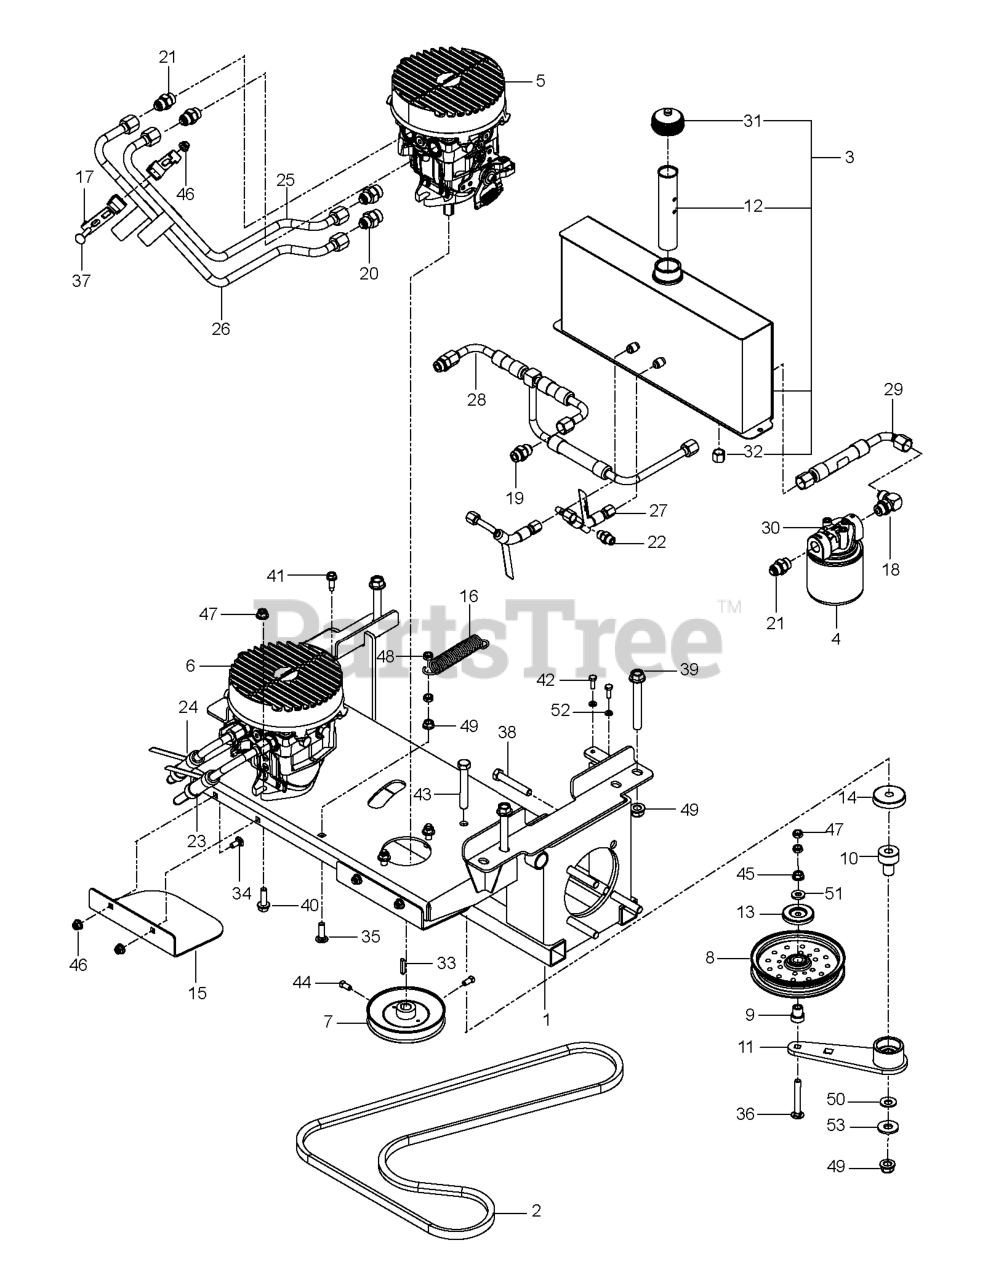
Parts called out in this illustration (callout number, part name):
1	FRAME, NYDR SUB, BLK
2	BELT, "B", 75.5"
3	ASSEMBLY, RESERVOIR, OIL
4	FILTER 25 MICRON
5	HG_PUMP, 12CC RT
6	HG_PUMP, 12CC LT
7	PULLEY, PUMP 15MM
8	IDLER, FLAT, 5.5"
9	PIVOT, IDLER
10	PIVOT, BEARING
11	ARM, IDLER, STEEL, W/BGS
12	TUBE, ANTI-SPLASH
13	DUST SHIELD
14	SHIELD, DUST
15	SHIELD, PULLEY, BLK
16	SPRING, PUMP
17	ASM, VIB, HYDRO HOSE
18	ELBOW, 90 DEGREE
19	FITTING, HYDRO
20	CONNECTOR, STRAIGHT
21	FITTING, STRAIGHT F6400-8-8-0
22	STRAIGHT FITG
23	LINE, RT A
24	LINE, RT B
25	LINE, LT A
26	LINE, LT B
27	LINE, CHARGE
28	LINE, CASE
29	LINE, SUCTION
30	FILTER HEAD
31	CAP, HYDRAULIC
32	NUT 9/16-18 JIC CAP
33	KEY.PARALLEL
34	RP BOLT 5/16-18 X3/4 ZN/YEL GR
35	BOLT.3/8-14X1.25
36	BOLT
37	BOLT
38	HCS 1/2-13 X 2-3/4 GD 5 ZD
39	HHFS 1/2-13 X 4.0 GD8 ZD
40	HHFS 3/8-16 X 1.25 GD 5
41	RP BLT 5/16-18 X 1 THRD FORM D
42	BOLT
43	HCS 1/2-13 X 3-1/4 GD 5 ZD
44	SCREW 5/16C X 5/8 SQ HEAD
45	NUT 3/8C WHIZ
46	5/16-18 NYLOC FLANGE NUT
47	NUT 3/8-16 HEX FLG NYLOC ZD
48	NUT HEX 3/8-16 NYLON, THIN
49	NUT, 1/2-13 HEX FLG NYLOC ZD
50	CONTACT BELLSPR 1/2
51	WASHER, 3/8 THICK
52	LOCKWASHER 1/4"
53	WASHER.9/16 X 1 3/8 X 12 GA.
